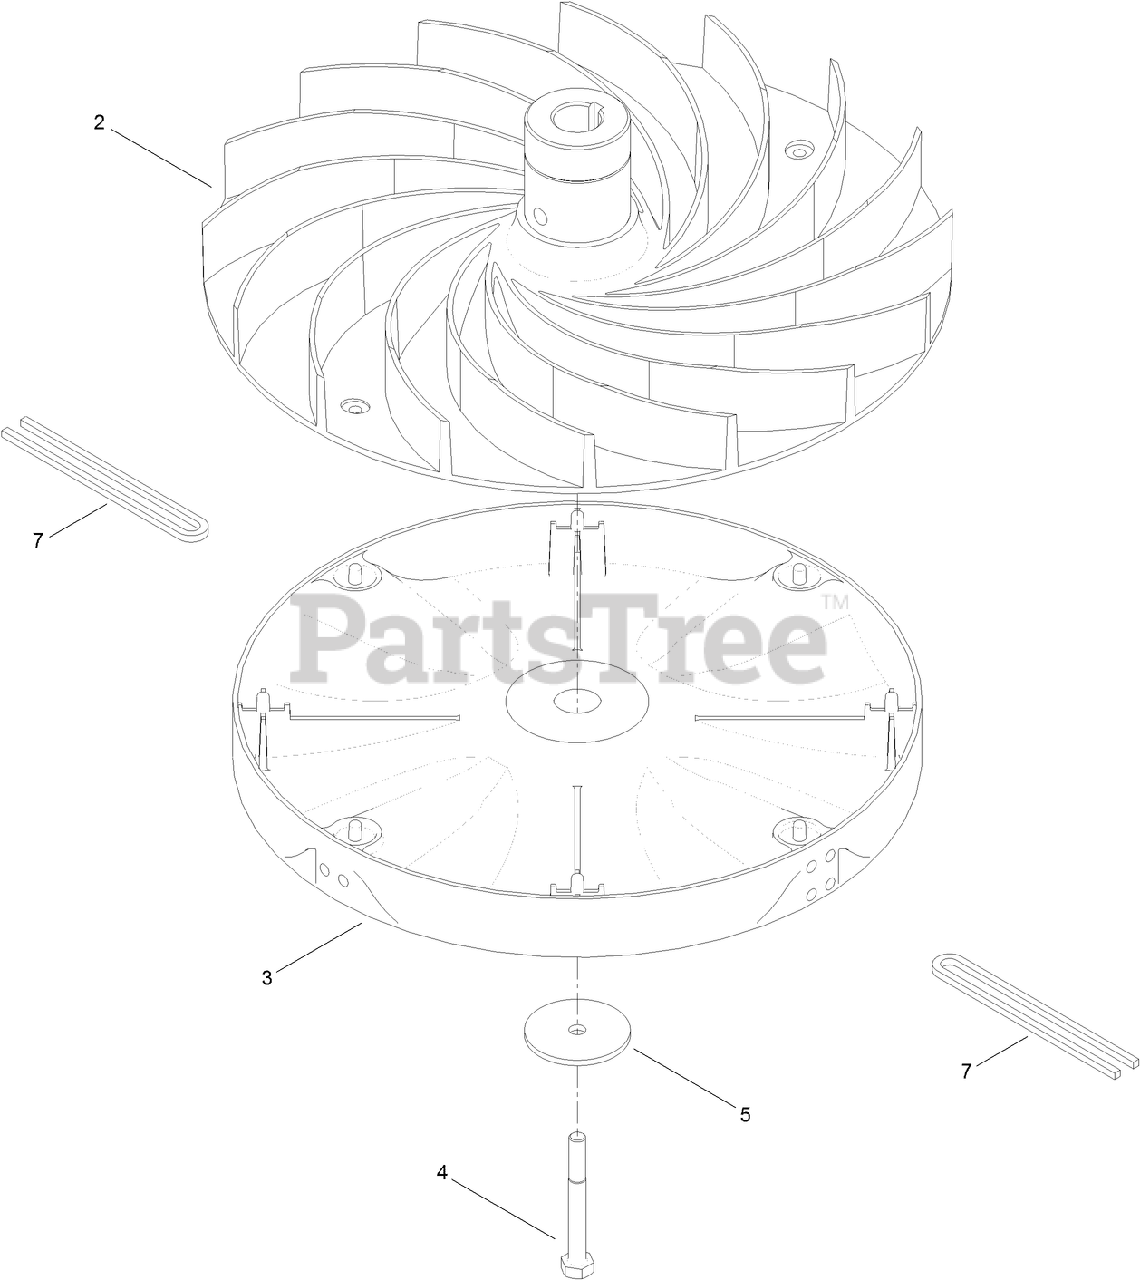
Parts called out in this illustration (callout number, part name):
2	IMPELLER
3	DISC-CUTTING
4	BOLT-HH
5	DISC-SPRING
